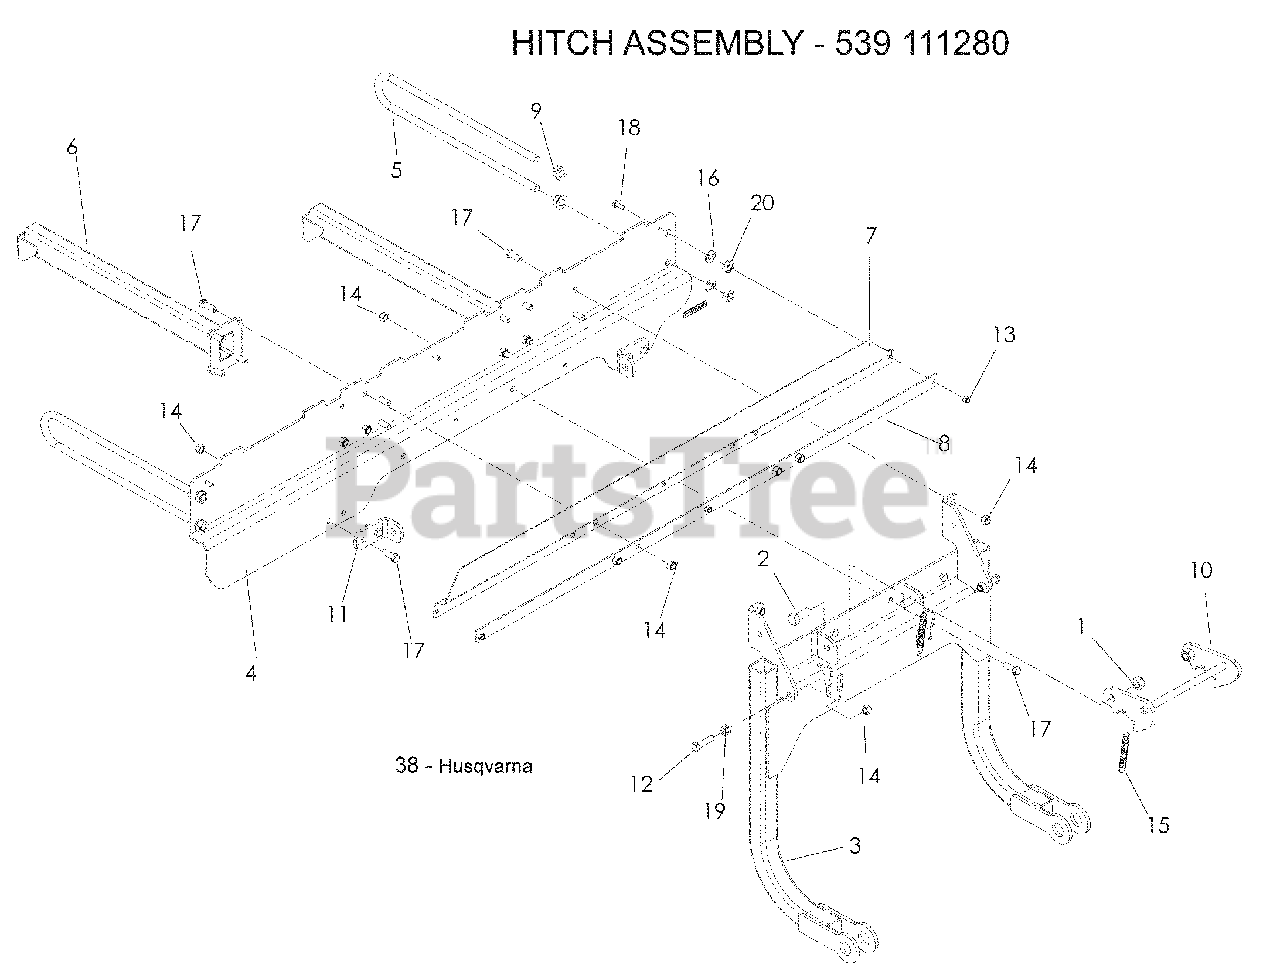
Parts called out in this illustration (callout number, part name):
1	NUT ½-13 HEX NYLOC
2	HCS ½-13 x 1¼
4	MOUNT Z BRACE
5	SUPPORT, OUTER
6	SUPPORT ARM
7	SEAL, RUBBER
8	SEAL STRAP
9	NUT ½ -13, WHIZLK
11	BRACKET, SUPPORT
12	HCS 3/8-16 x 1½
13	NUT ¼-20 HEX NYLOC
14	NUT 3/8-16 HEX NYLOC
16	LOCKWASHER ½
17	HCS 3/8-16 x 1
18	HCS ¼-20 x ¾
19	NUT 3/8-16 HEX WHIZLK
20	NUT ½-13 JAM
